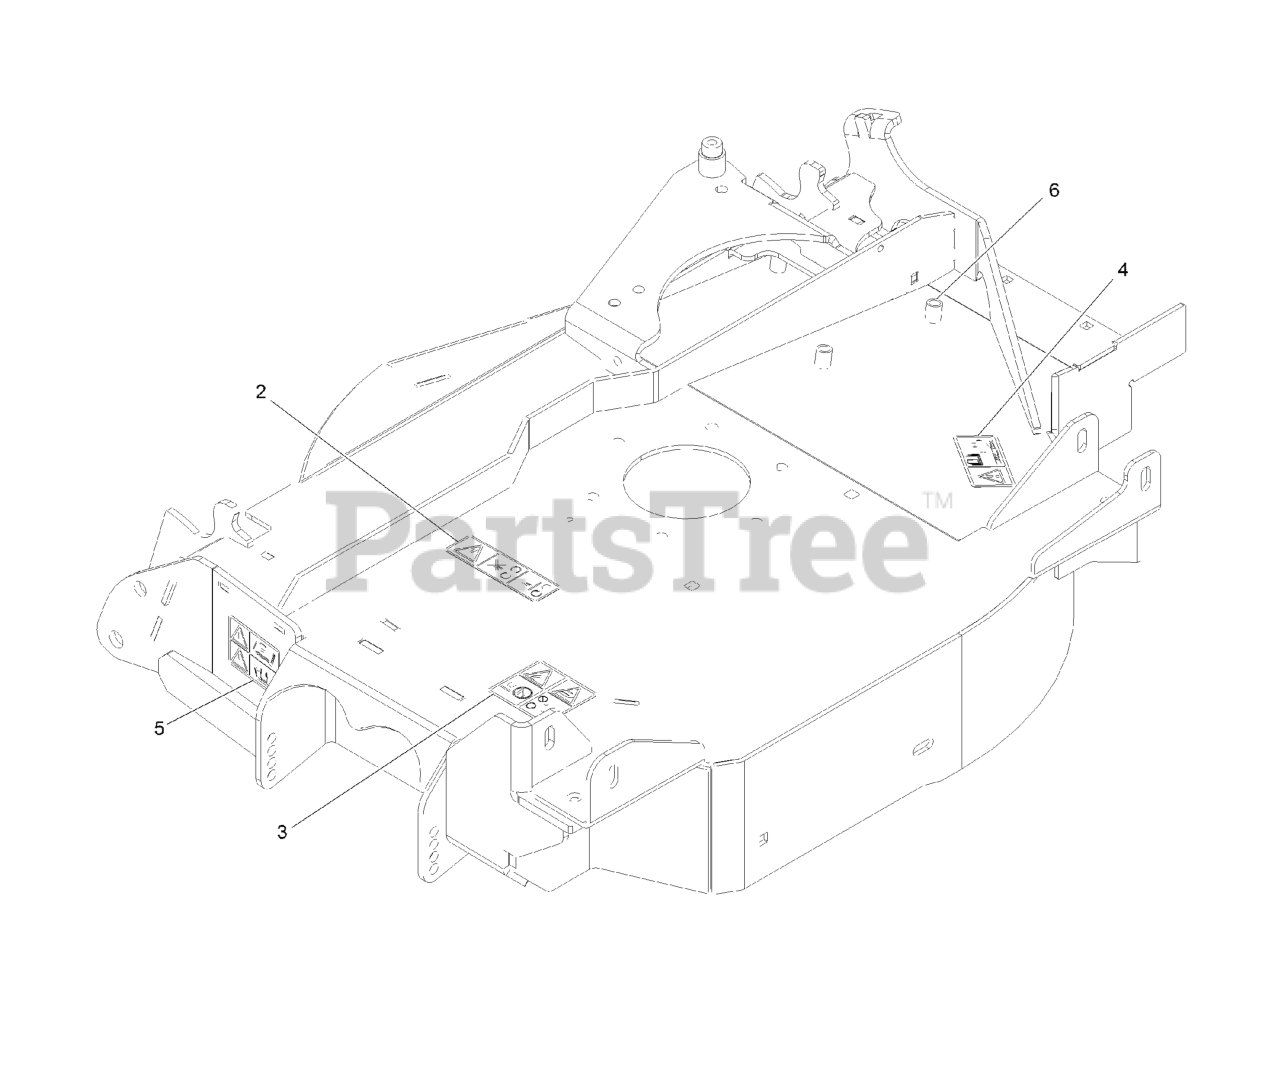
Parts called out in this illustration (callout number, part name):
2	DECAL-COVER, MISSING
3	DECAL-DANGER, THROWN OBJECT
4	DECAL-TORQUE, BOLT
5	DECAL-WARNING, PINCH POIN
6	NUT-CLINCH
